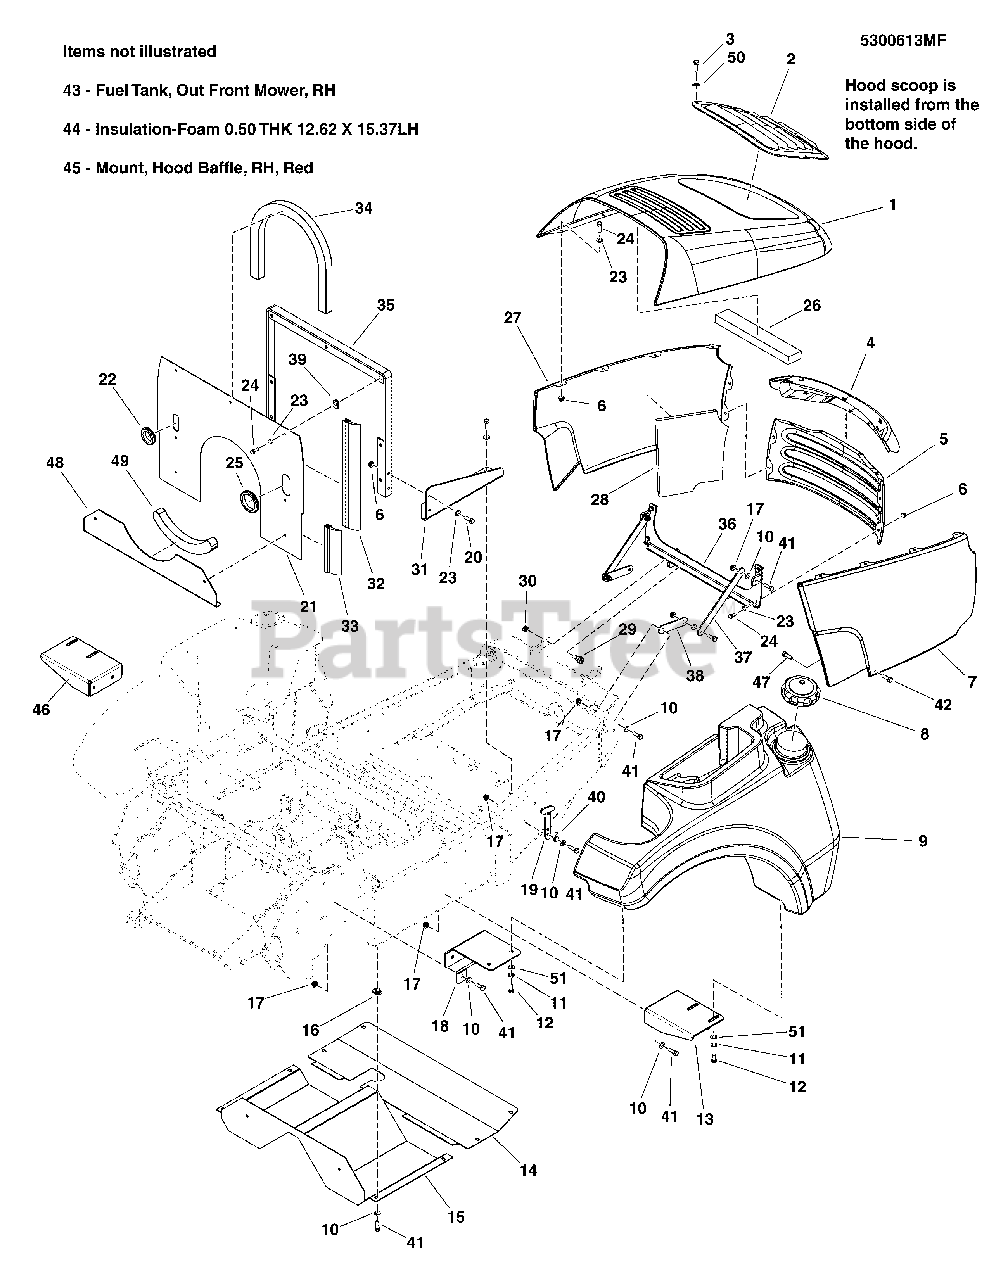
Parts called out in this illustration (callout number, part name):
1	HOOD, BOXED, S800X - SPR RED (SV)
2	SCOOP, HOOD, OUTFRONT MOWER
3	RIVET, Pop
3	POP RIVET, 3/16" X .575"(.251-.375GP)BLK
4	MACHINED BLACK LENS, OUT FRONT MOWER
5	GRILLE, PERF METAL, OUT FRONT MOWER - RED
6	NUT, 1/4-20, GR5 Flanged Nylock, Zinc/Clear
7	PANEL-SIDE, 18GA LEGACY - PLAIN
8	FUEL CAP, 3-1/2", MANAGED VENT OUT, 12"
9	FUEL TANK, OUT FRONT MOWER, LH
10	WASHER, 5/16
11	WASHER, Flat
12	CAPSCREW, Hex Head, 5/16-18 x 3/4
13	WELD, TANK MOUNT, LH - RED
14	PLATE, GUARD, PERFORATED - RED
15	DEBRIS GUARD, PUMP - RED
16	CLIP, BODY , 5/16-18 FOR 7 GA.
17	NUT, Ny Lock Flange, 5/16-18
18	MOUNT, FUEL TANK WELDMENT - FRONT - RED
19	STRAP, Hood Rubber
20	BOLT, 1/4-20 X 1", GD
21	PLATE, HOOD BAFFLE, LOWER - RED
22	GROMMET, 1-1/4"
23	WASHER, 1/4, Flat, GR5 Zinc/Clear
24	CAPSCREW, Hex Flange, Whiz Lock, 1/4-20 x 5/8
25	GROMMET, 2" ID
26	FOAM HOOD SEAL, OUT FRONT MOWER
27	PANEL-SIDE, 18GA LEGACY - PLAIN
28	INSULATION-FOAM 0.50 THK 12.62 X 15.37RH
29	BOLT, 3/8-16 X 3/8", 1/2" SHOULDER
30	NUT, Hex, Side Lock, 3/8-16
31	MOUNT, HOOD BAFFLE, LH - RED
32	SEAL, WIPER, CLIP ON, 14.75
33	SEAL, WIPER, CLIP ON, 6
34	SEAL, FLYWHEEL SCREEN, FOAM
35	WELD., HOOD BAFFLE FRAME - RED
36	WELD, HOOD MOUNT - RED
37	LINK, HINGE, LONG - RED
38	LINK, HINGE, SHORT - RED
39	BODY CLIP, 1/4-20 X 1/2" DEEP
40	HOOK-.125DIA WIRE GR CAT STRAP YELLOW
41	CAPSCREW, Hex Head, 5/16-18 X 1
42	BINDING, Internal Thread, #8-32 X 1/2
46	WELD, TANK MOUNT, LH - RED
47	SCREW-HEX SERR FLNG LK # 8-32X0.375 YEL
48	PLATE HOOD BAFFLE, BOTTOM - RED
49	FOAM, ENGINE FAN SEAL, OUTFRONT, BOTTOM
50	WASHER, #10 SAE
51	WASHER, 5/16" GD.9 FLAT
